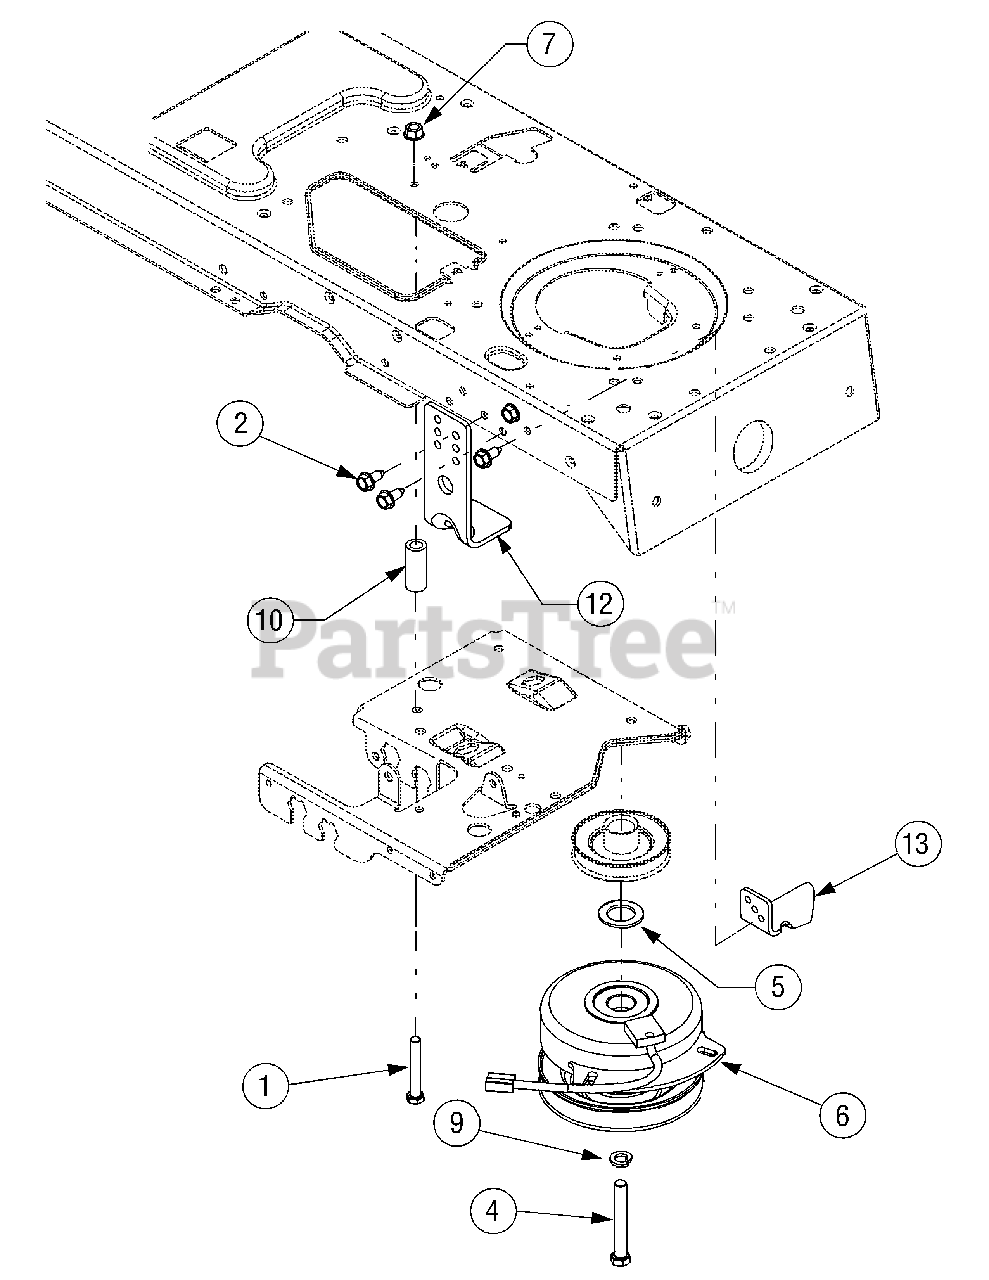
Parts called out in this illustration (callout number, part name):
1	Screw, 3/8-16 x 2.25 GR5
2	Screw, 5/16-12, .75
3	Screw, 5/16-18, .75
4	Screw, Hex Cap, 7/16-20 x 3.50 GR5
5	Washer, Flat, 1.031 x 1.62 x .095
6	Clutch, PTO
7	Nut, Hex. Nylon Lock, 3/8-16
8	Washer, Lock, 7/16, Regular Duty
9	Washer, Lock, 7/16
10	Spacer, 3/8 x 1.54
11	Washer, Flat, 1.031 x 1.62 x .095
